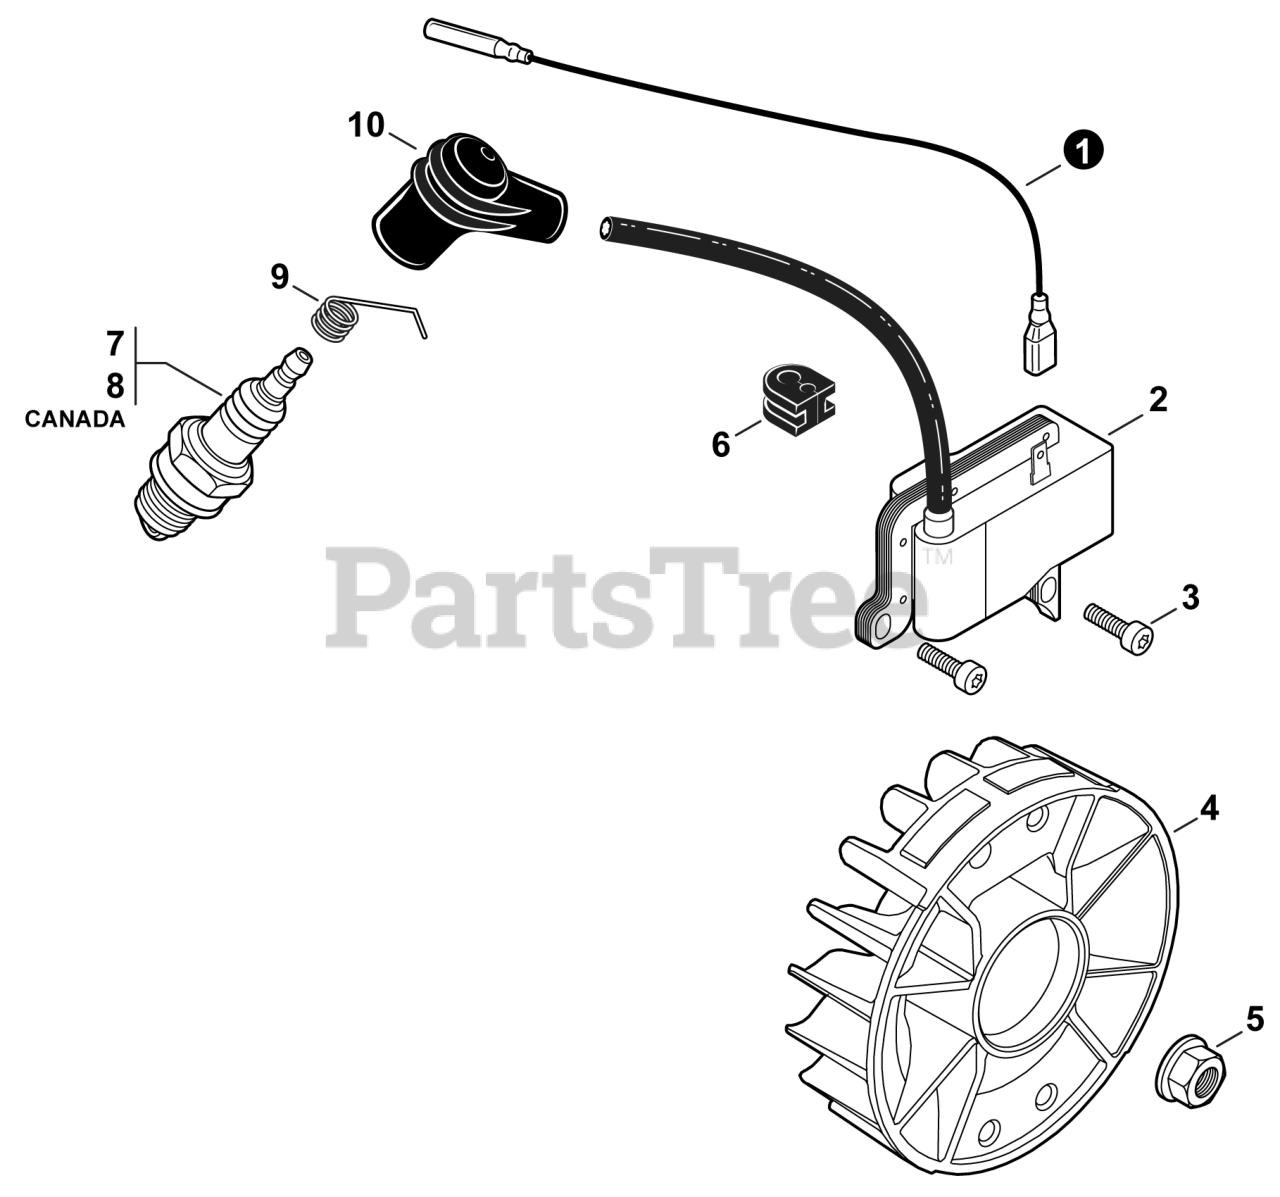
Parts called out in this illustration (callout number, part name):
1	LEAD L= 470
2	COIL, IGNITION
3	BOLT, TORX 5x20
4	FLYWHEEL
5	NUT, FLANGE 10x1.25
7	SPARK PLUG - BPM6Y
8	SPARK PLUG - BPMR6Y
9	TERMINAL, SPARK PLUG
10	CAP, SPARK PLUG
